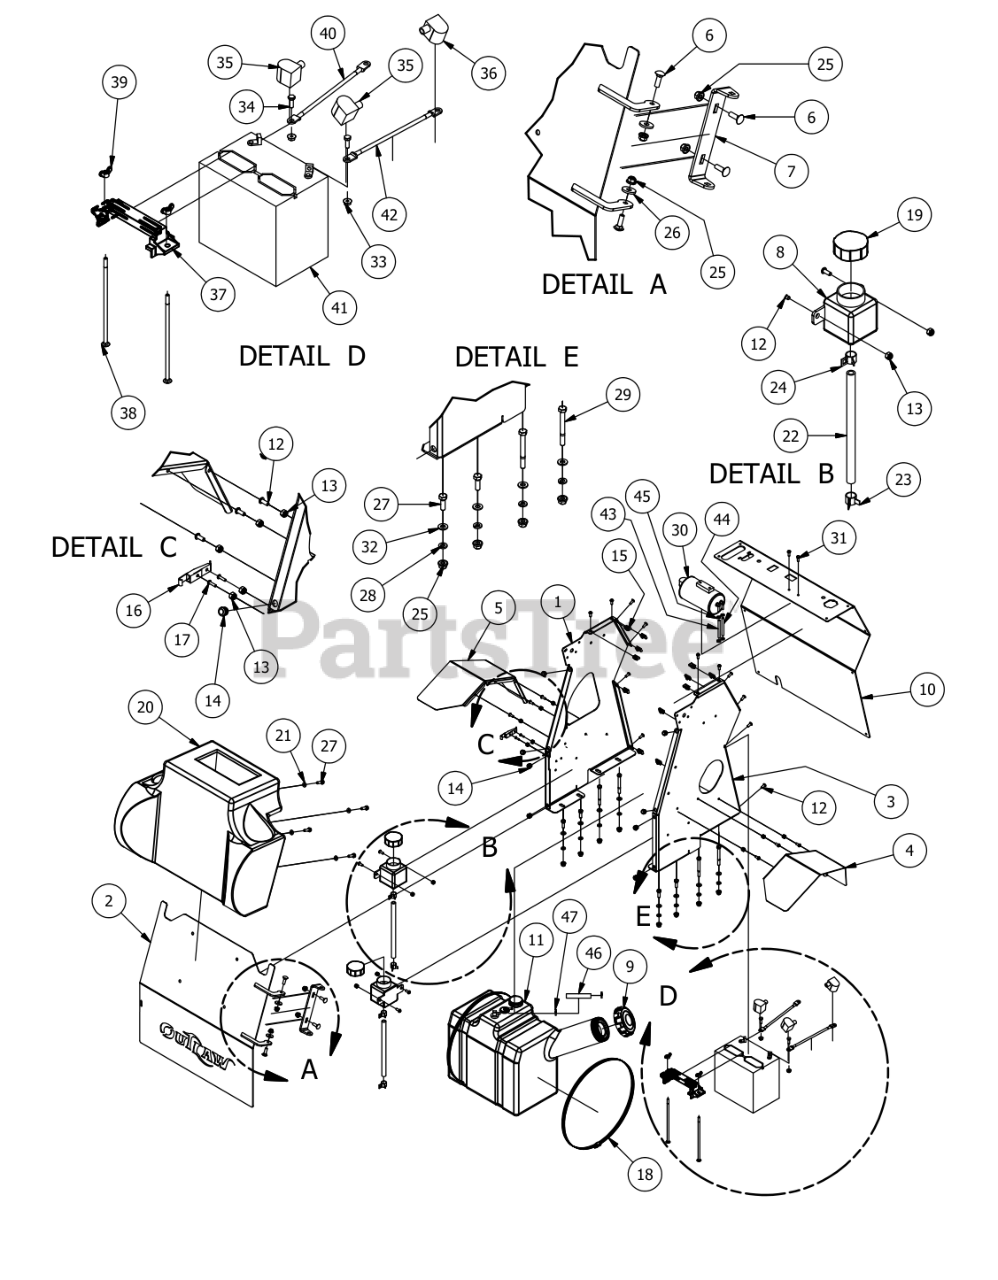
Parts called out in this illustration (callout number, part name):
1	2015 Podium Panel Left
2	Door Panel Assembly
3	2015 Podium Panel Right
4	Fender (Right Side)
5	Fender (Left Side)
6	5/16" x 1" Carriage Bolt
7	Back Cover Hinge Bracket
8	350ml Expansion Tank
10	2015 Podium Front Panel
12	1/4" x 5/8" BS C/S 18-8 SS
13	1/4" Nylock Nut
14	5/8 Round Insert
15	1/4-20 Cage Nut
16	Steel Pump Cover Latch
17	10-24 X 5/8 BS Button Head Bolt
18	Fuel Tank Clamp-Stand On
19	Hydraulic Tank Cap
20	Cushion-2015 Stand On Mower
21	1/4" Flat Washer
22	3/8" Clear Hose
23	1/2 Hose Clamp
24	3/8" Hose Clamp
25	5/16" Nylock Flange Nut Zinc
26	.360 ID Plastic Washer
27	5/16" x 1" Bolt
28	5/16" Lock Washer
29	5/16" x 3" Hex Bolt
30	Carbon Canister
31	M6-1.0 X 16MM Hex Bolt
32	5/16" Flat Washer
33	1/4-20 Hex Flange Nuts Zinc w/Serrations
34	1/4-20 x 3/4 GR 5 Hex Bolts Zinc
35	Black Boot For Ground Cable
37	Battery Hold Down
38	1/4-20 X 8 Carriage Bolt
39	1/4" Wing Nut
40	Ground Cable
42	24" Red Battery Cable
43	1/4" Vinyl Tubing
44	3/16 Vinyl Tubing
45	3/16 Vinyl Clamp
46	1/4 Fuel Line
47	1/4 Fuel Hose Clamp
